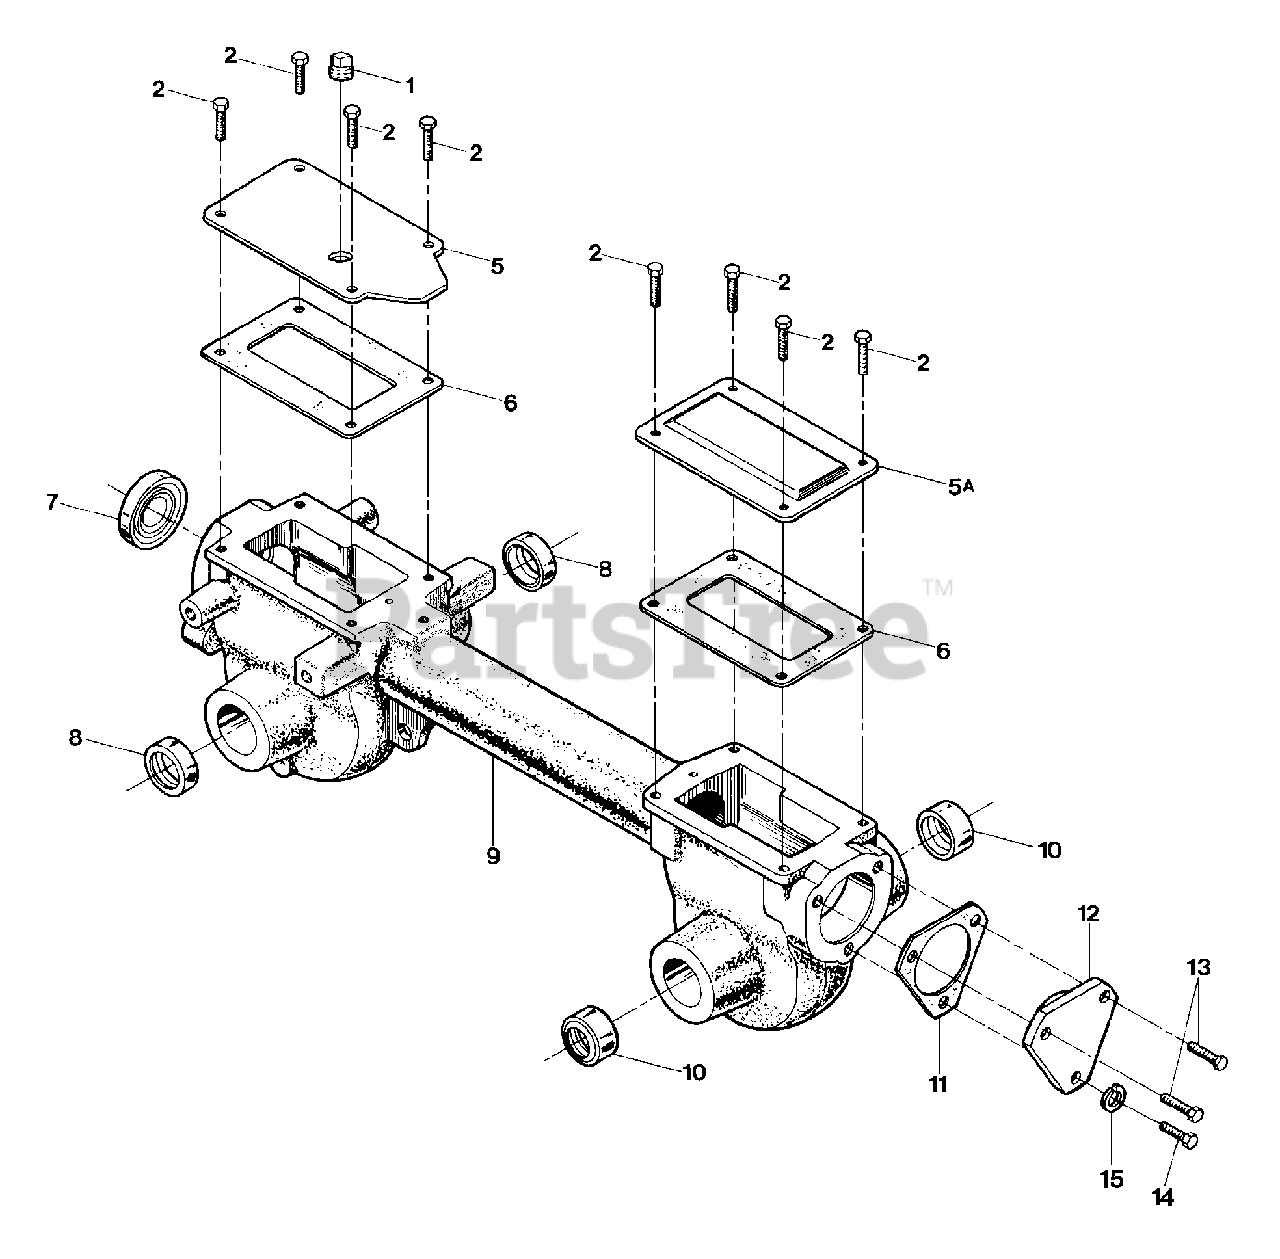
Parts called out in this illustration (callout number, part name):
1	Plug, Transmission Oil Fill
2	Hex Hd. Flange Screw, 5/16-18 x 5/8, Grade 5
5	Front Cover, Transmission
5A	Rear Cover, Transmission
6	Gasket, Housing Cover
7	Oil Seal, Drive Shaft
8	Oil Seal, Wheel Shaft
9	Transmission Housing Ass'y
10	Oil Seal, Tine Shaft
11	Bearing Cap Gasket, .010" thick
12	Rear Bearing Cap
13	Hex Hd. Flange Screw, 5/16-18 x 1
14	Hex Hd. Flange Screw, 5/16-18 x 3/4
15	Lock Washer, 5/16
